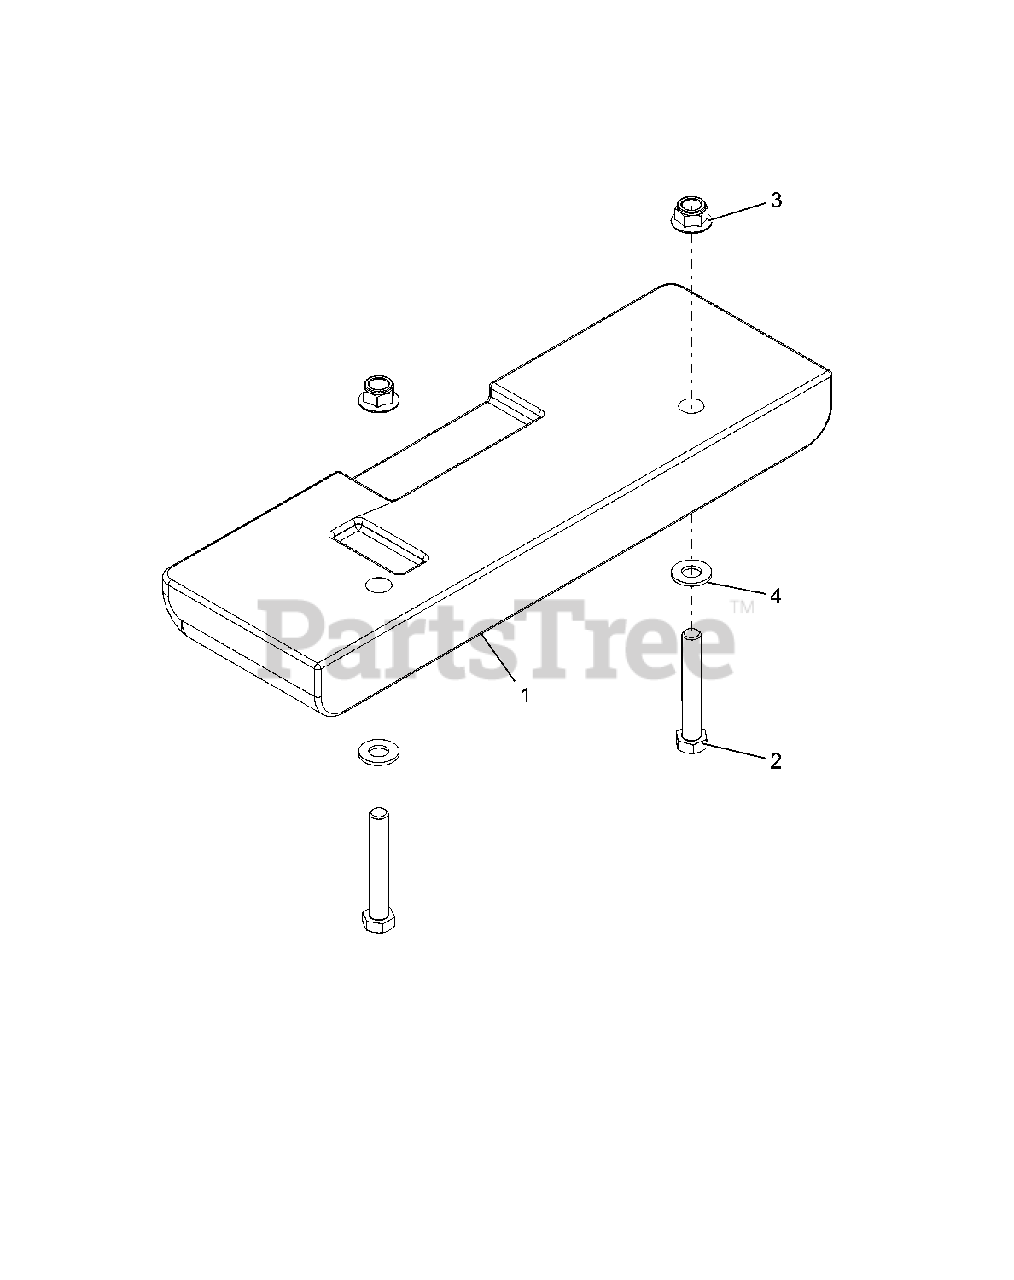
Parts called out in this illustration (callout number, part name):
1	WEIGHT, CAST IRON
2	@BLT-HEX .50-13X3.25 GR5 YWZC
3	@NUT-LK-NYL-FLG .50-13 YWZC
4	@WSHR-FL-STL.531X1.06X.095YWZC
